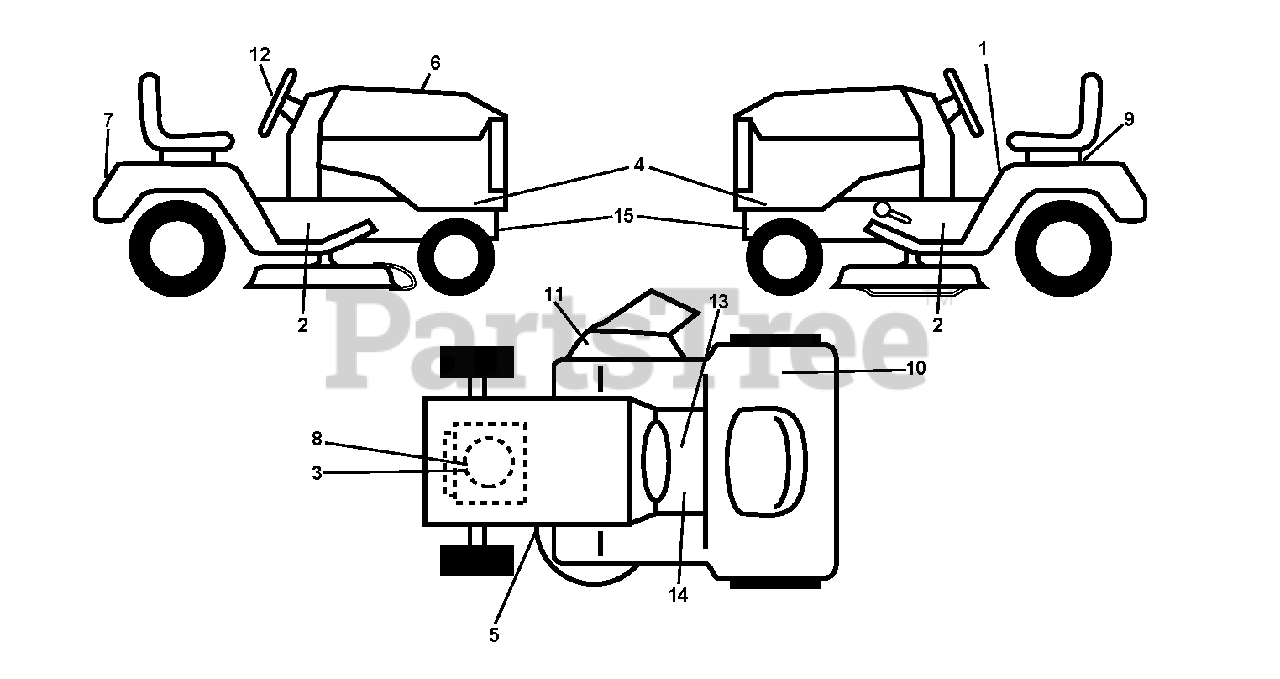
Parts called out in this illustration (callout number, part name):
6	DECAL DECAL.RPL.BSM21
9	DECAL BTRY SYMBOLS
10	Decal, 100 DB/CE
11	DECAL.WARN.DFLECT/CTFINGR.SRD
13	DECAL PARK BRAKE
